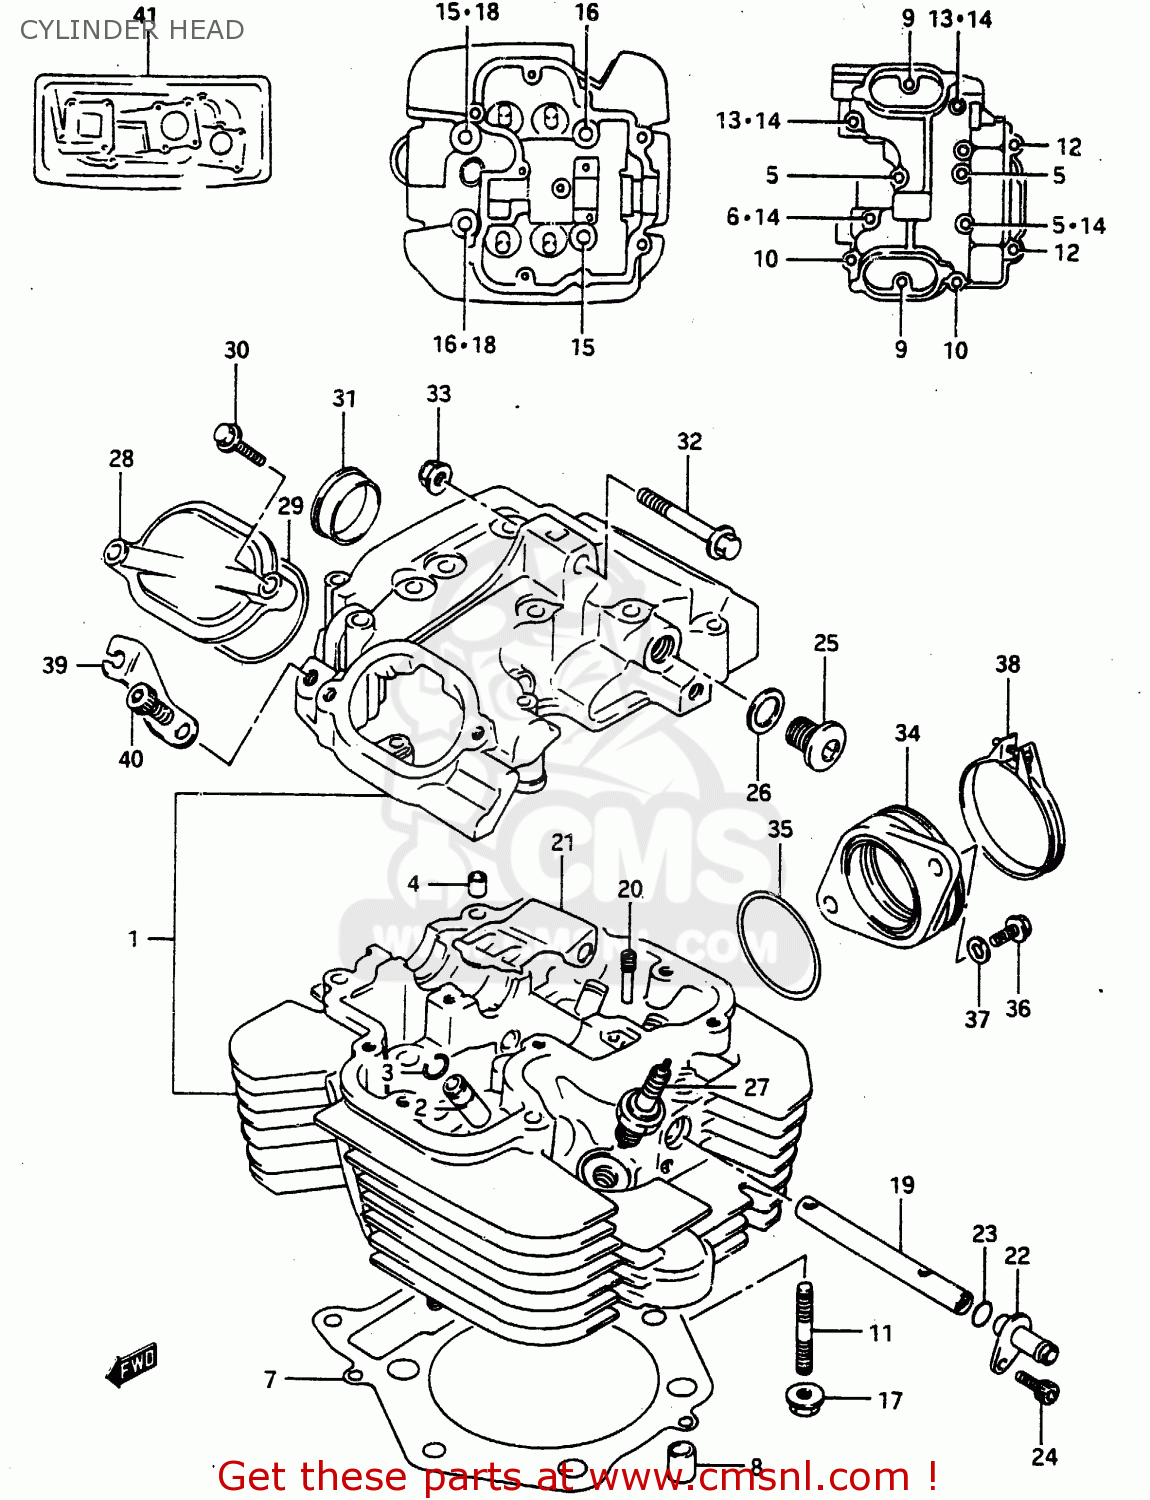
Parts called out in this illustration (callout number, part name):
1	HEAD ASSY, CYLINDER
2	GUIDE,VALVE
3	RING,SNAP
4	PIN(6.2X8X11)
5	BOLT ,6X60
6	BOLT 6X55
7	GASKET,CYLINDER HEAD (NAS)
8	PIN
9	BOLT 6X25
10	BOLT
11	STUD
12	BOLT(6X130)
13	BOLT ,6X60
14	GASKET(5.8X13X1.2) (NAS)
15	BOLT(10X190)
16	BOLT(10X215)
17	NUT 8MM
18	GASKET(10.5X22X2) (NAS)
19	PIPE,CYLINDER HEAD OIL
20	SCREW (L:19.5)
21	PLATE,CYLINDER HEAD CHAMBER
22	UNION,CYLINDER HEAD OIL
23	O RING
24	BOLT
25	PLUG
26	GASKET(14X19.2X2) (NAS)
27	SPARK PLUG DP9EA-9
28	CAP,INSPECTION
29	O RING(D:2.4,ID:23)
30	BOLT
31	PLUG(OD:30)
32	BOLT
33	NUT
34	PIPE,INTAKE
35	O RING(D:2.4,ID:45.7)
36	PLUG ,6X20
37	WASHER
38	CLAMP
39	LEVER,DECOMP SHAFT RH
40	BOLT
41	GASKET SET
